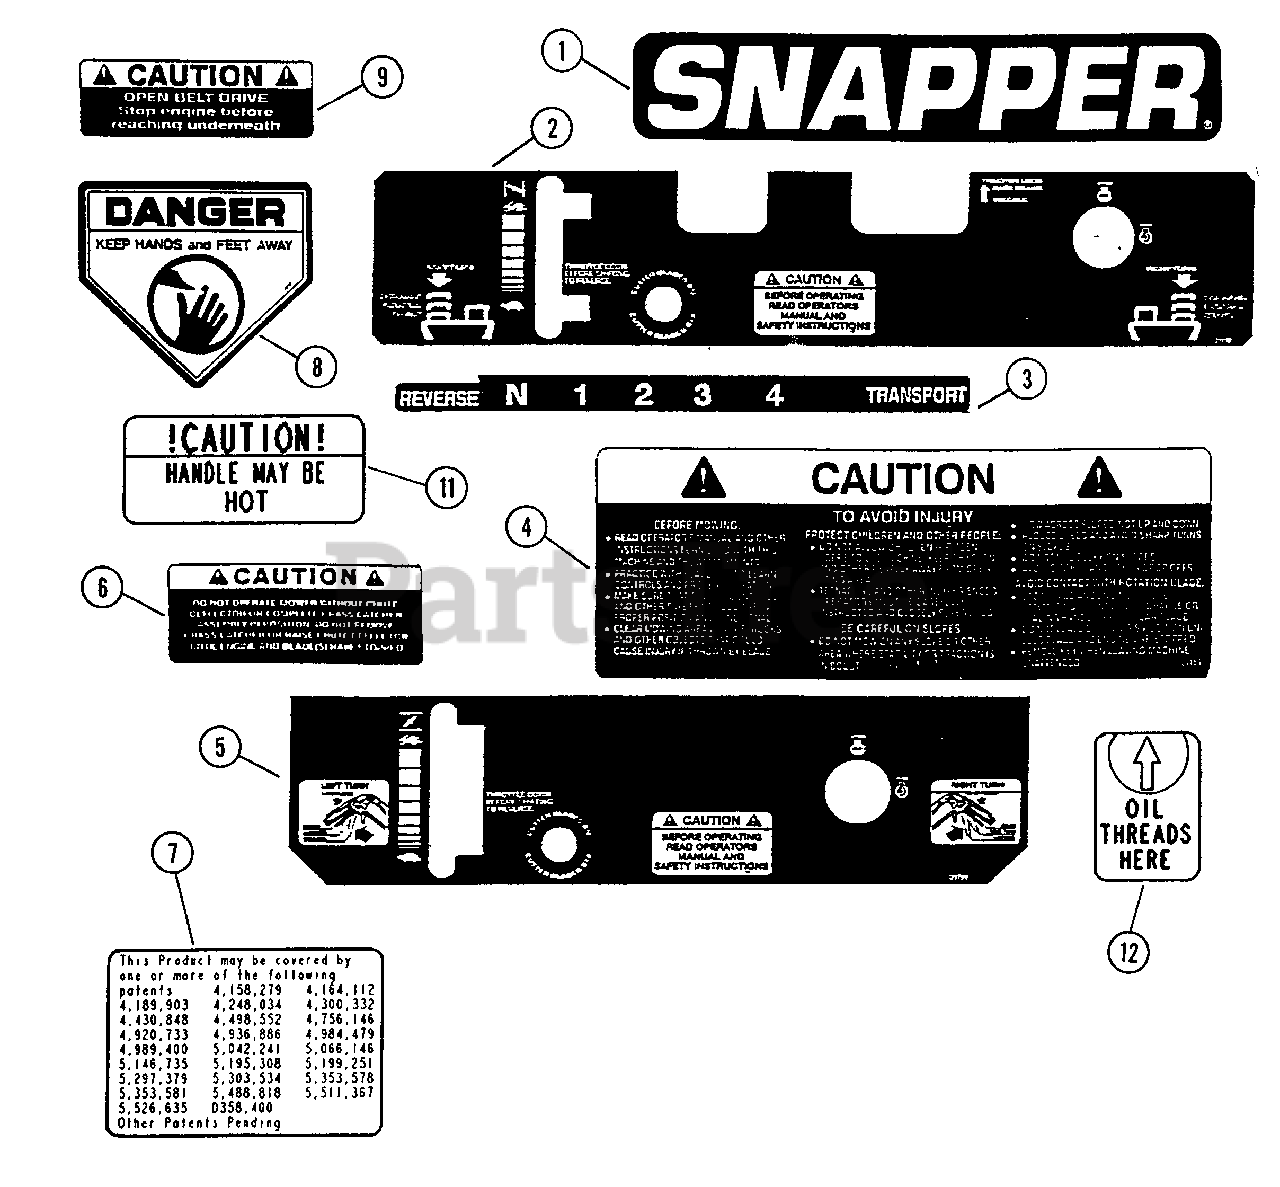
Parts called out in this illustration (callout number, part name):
1	DECAL, SNAPPER
2	DECAL, Console (Loop Handle)
3	DECAL, Shift Quadrant
4	DECAL, Caution
5	DECAL, Console (Pistol Grip Handle)
6	DECAL, Caution
7	DECAL, Patent Numbers
8	DECAL, Warning
9	DECAL, Caution
11	DECAL, Caution
12	DECAL, Oil
